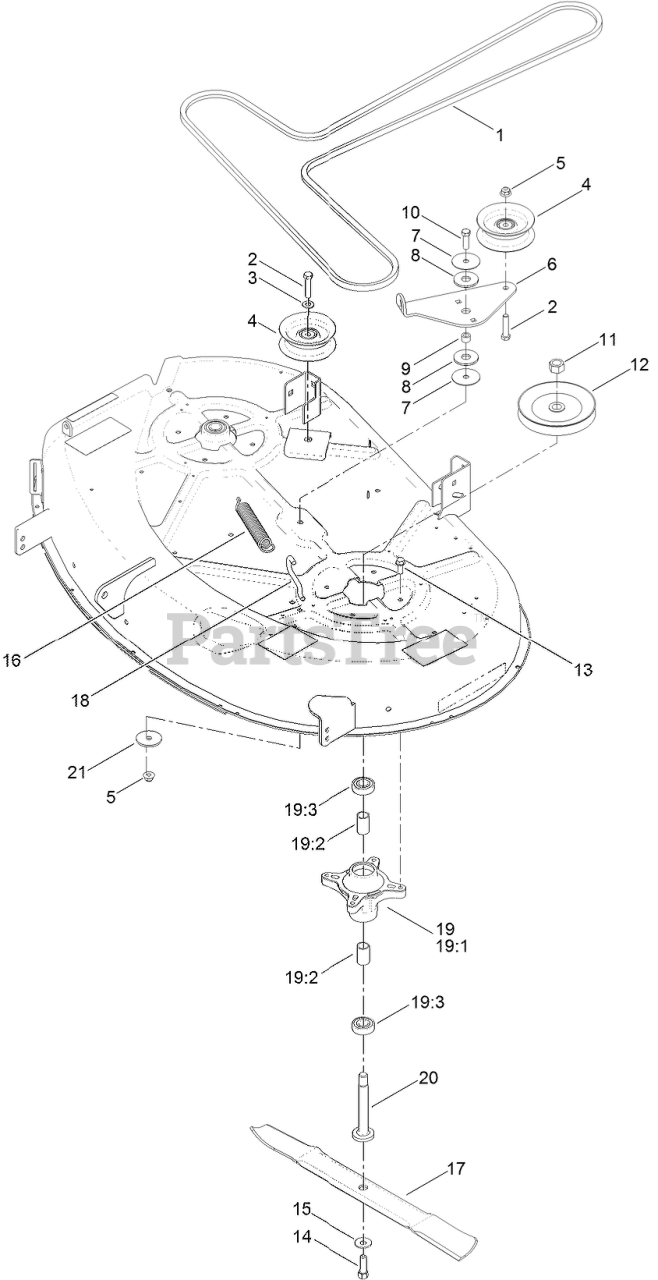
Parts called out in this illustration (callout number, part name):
1	V-BELT
2	SCREW-HH
3	WASHER-FLAT
4	PULLEY-IDLER, FLAT
5	NUT-HF, NI
6	ARM-IDLER
7	WASHER
8	WASHER-FRICTION, COMPOSITE
9	SPACER
10	SCREW-HH
11	NUT-HEX
12	Pulley
13	SCREW-TAPTITE
14	SCREW-HH
15	WASHER-BELLEVILLE
16	SPRING-EXTENSION
17	BLADE-HIGH LIFT
18	HOOK-RETURN, SPRING
19	SPINDLE ASM
19:1	SPINDLE
19:2	SPACER
19:3	BEARING-BALL
20	SHAFT-SPINDLE
21	WASHER-REBOUND
